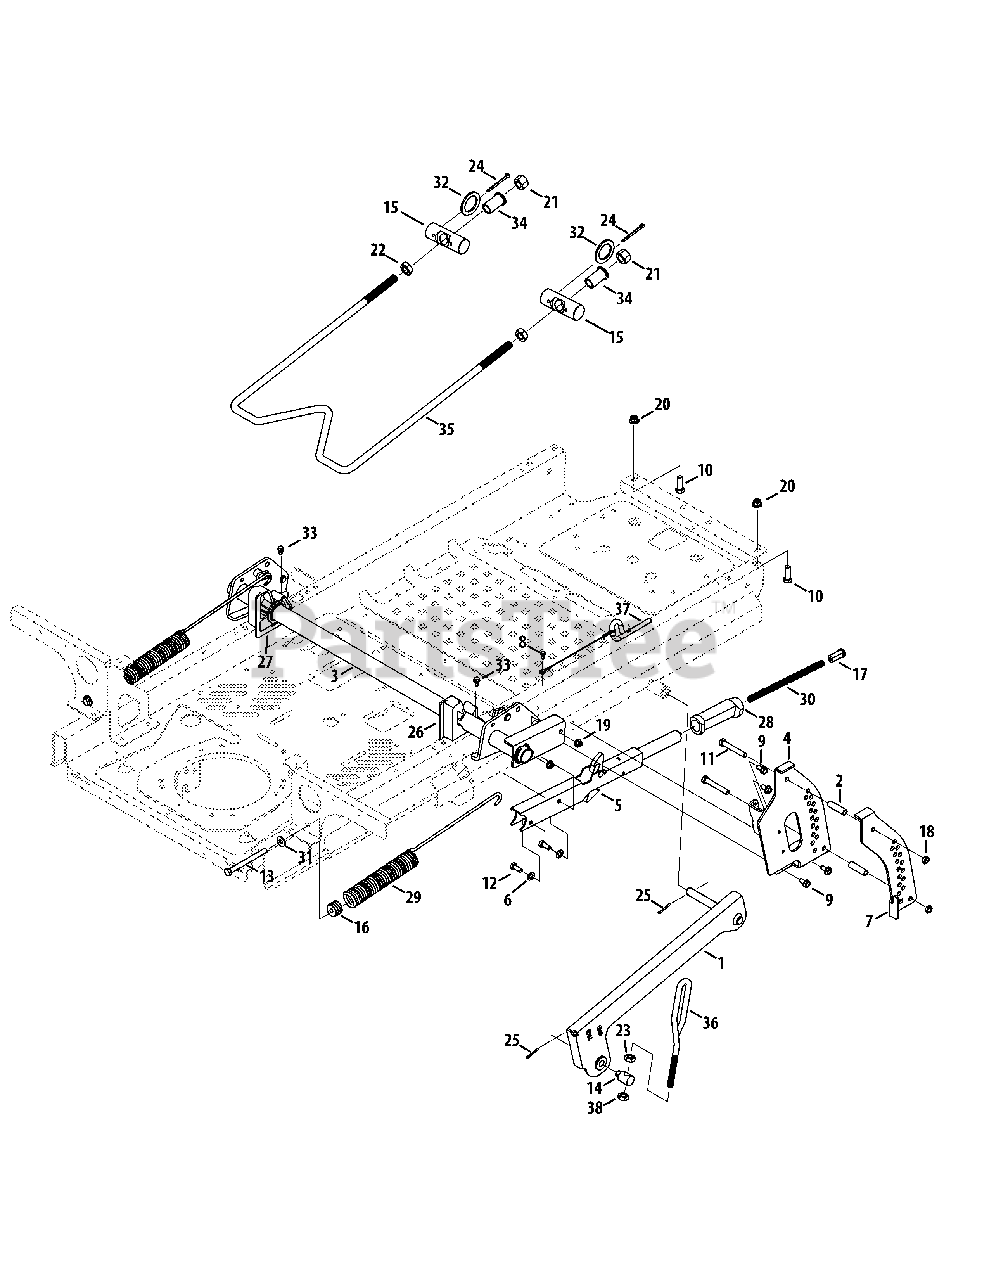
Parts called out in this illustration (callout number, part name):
1	Lift Arm, RH
1	Lift Arm, LH
2	Spacer, .386 x .63 x 1.75
3	Deck Lift Shift Assembly
4	Index Bracket Assembly
5	Latch Handle Assembly
6	Flat Washer .330 ID x .630 OD
7	Outer Index Bracket
8	Screw, #10-16, .50
9	Hex Washer Screw, 5/16-18 x .750
10	Hex Screw, 3/8-16 x 1.00
11	Hex Head Screw, 3/8-16 x 2.50
12	Hex Cap Screw, 5/16-18 x .75
13	Hex Screw, 3/8-16 x 4.25
14	Ferrule, .496 x .528
15	Pivot Pin, 1.25
16	Spring Insert
17	Handle Button
18	Jam Lock Nut, 3/8-16
19	Flange Lock Nut, 5/16-18
20	Flange Lock Nut, 3/8-16
21	Nylock Nut, 5/8-11
22	Jam Nut, 5/8-11
23	Nut, Jam, 1/2-13
24	Cotter Pin, 3/16 x 2.0
25	Cotter Pin 1/8 x 1.25
26	Deck Lift Bracket
27	Deck Lift Bracket, LH
28	Grip, Deck Lift Handle
29	Extension Spring, 1.485 OD x 17.58
30	Spring, Compression, .4 x 8.52
31	Flat Washer, .385 x .870 x .092
32	Flat Washer, 1.875 x 1.38 x .097
33	Shoulder Screw, .500 x 1/4-20
34	Flange Bearing, .875 x .702 x 1.10
35	Deck hanger Rod, 5/8
36	Lift Adjust Link
37	Lock Rod, .375
38	Hex Nut, 1/2-13
